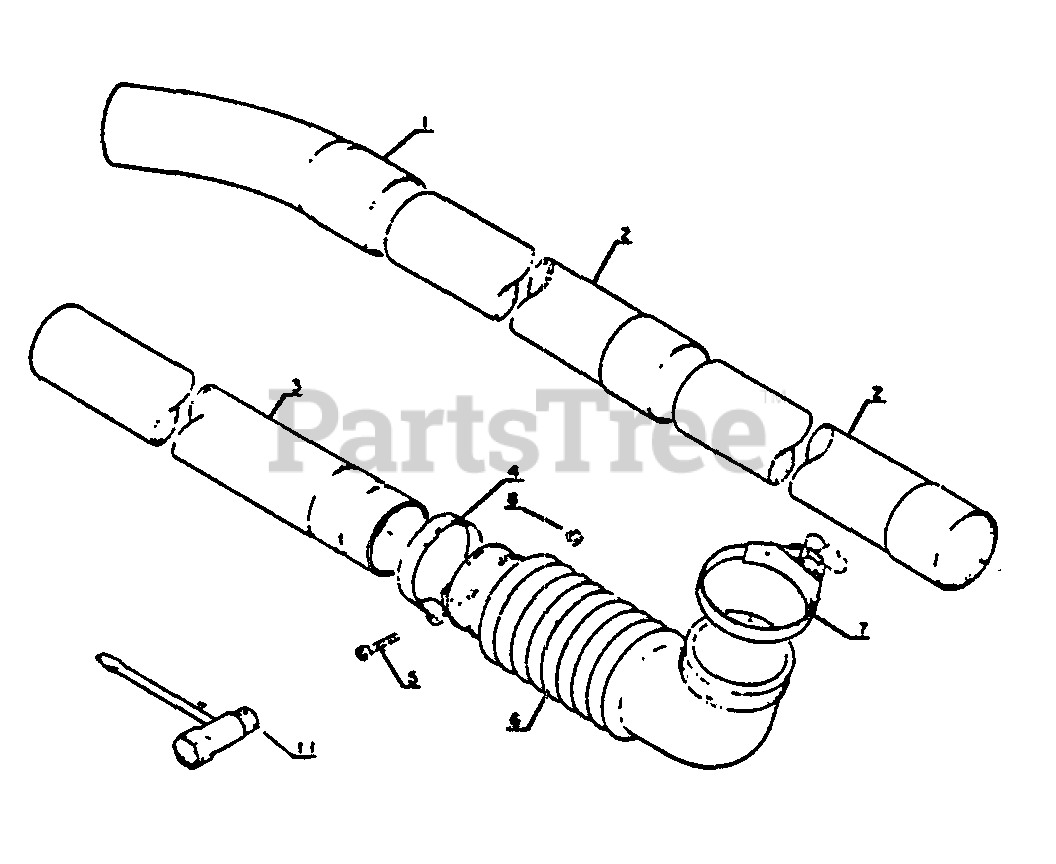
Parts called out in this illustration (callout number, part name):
1	TUBE, BLOWER - CURVED
2	TUBE, BLOWER - STRAIGHT
3	TUBE, BLOWER - SWIVEL
4	CLAMP
5	SCREW - 5X25
6	TUBE, BLOWER - FLEXIBLE
7	CLAMP
11	T-WRENCH - 13X19mm
